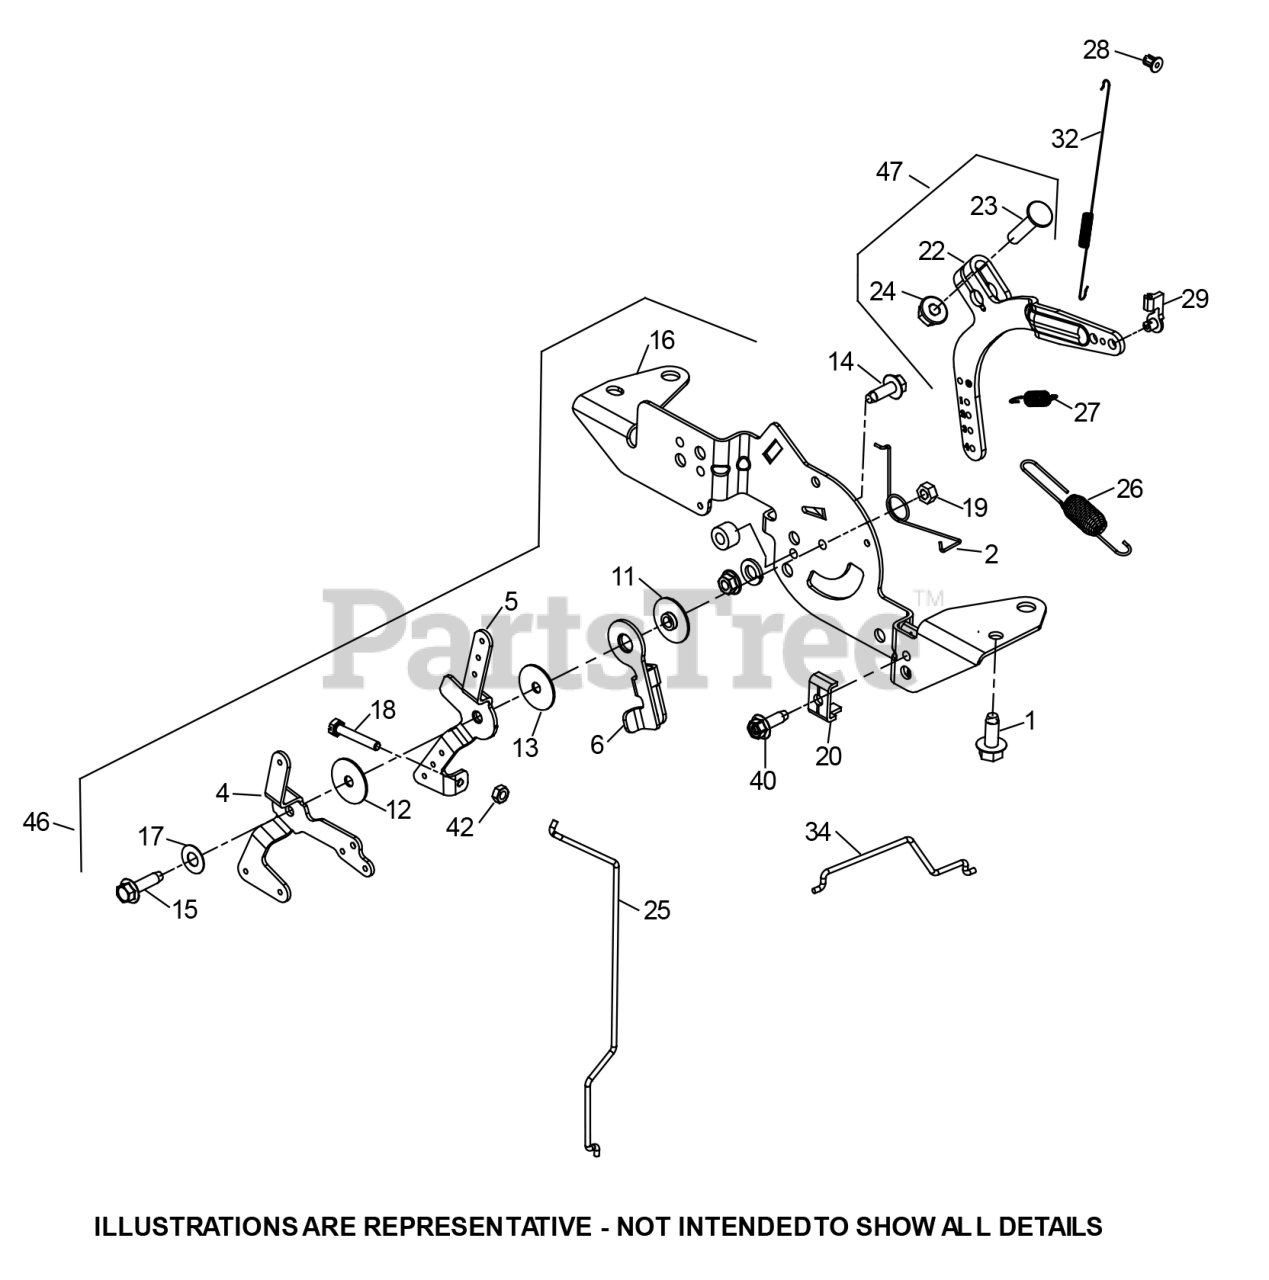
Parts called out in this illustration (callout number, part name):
1	SCREW-THREAD FORMI
2	SPRING-CHOKE RETRN
5	LEVER-THROTTLE CON
6	LEVER-THROTTLE ACT
11	SPACER-CONTROL ASSEMBLY
15	THREAD FORMING SCREW
16	SPEED CONTROL BRACKET
22	LEVER-GOVERNOR ASSEMBLY
23	BOLT-RD HD SQ NECK
24	HEX FLANGE NUT
25	CHOKE LINKAGE
26	GOVERNOR SPRING
27	GOVERNOR SPRING
29	BUSHING-RETAINING
32	LINKAGE SPRING
34	THROTTLE LINKAGE
40	THREAD FORMING SCREW
46	SPEED CONTROL ASSEMBLY
47	LEVER-GOVERNOR ASSEMBLY
